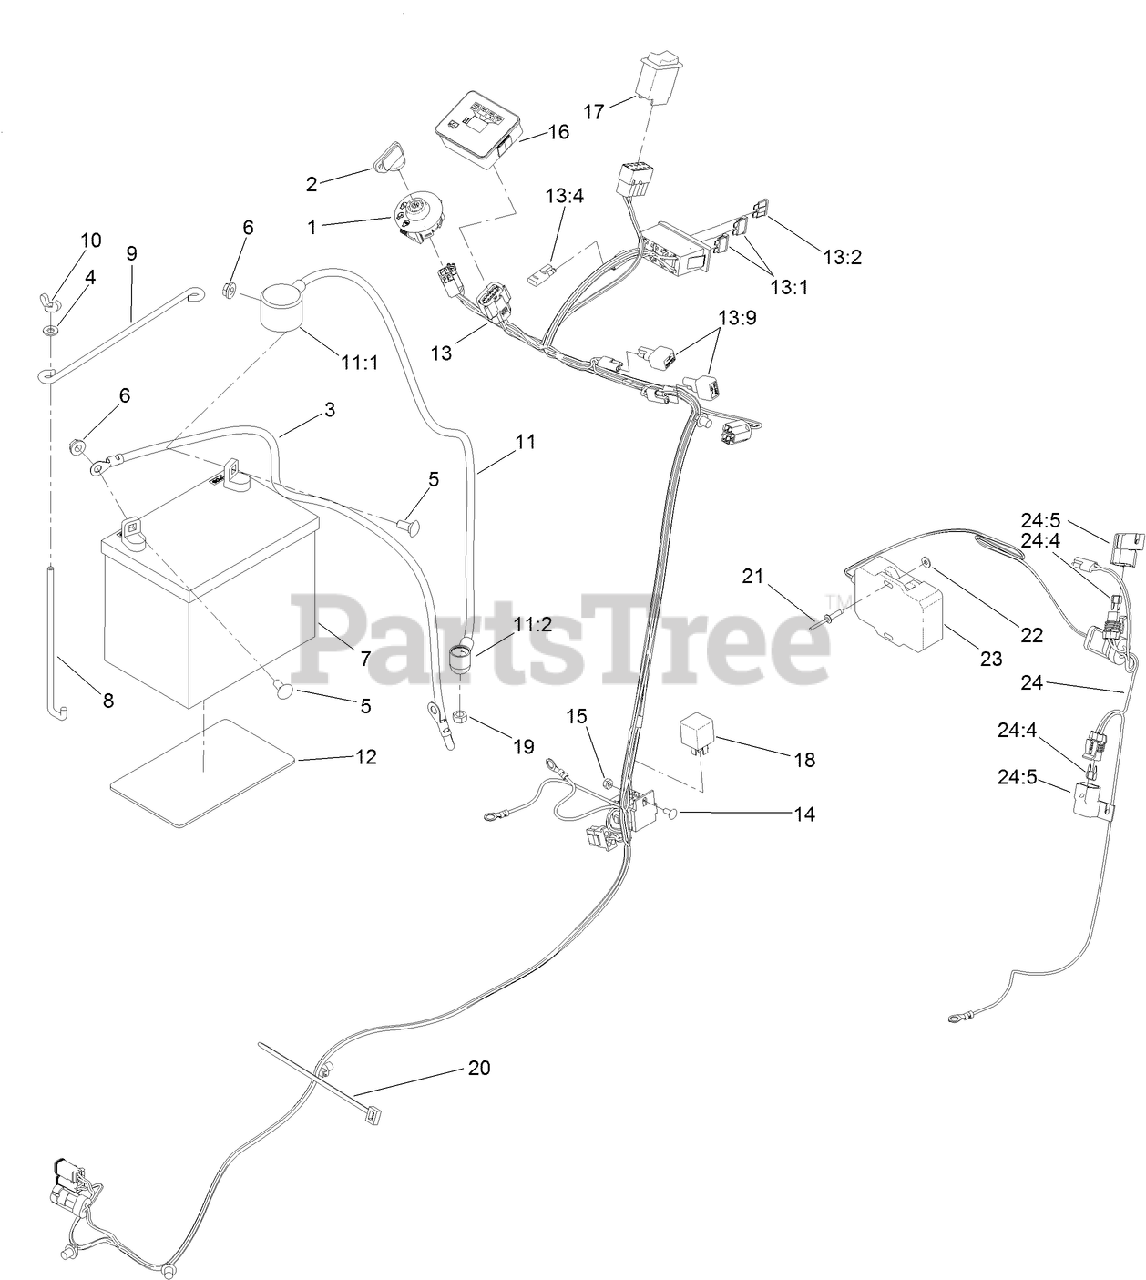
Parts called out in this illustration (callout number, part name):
1	SWITCH-IGNITION
2	KEY-IGNITION
3	CABLE-BATTERY, NEGATIVE
4	WASHER-FLAT
5	BOLT-CARR
6	NUT-HF
7	BATTERY (340 CCA, WET)
8	POST-BATTERY
9	ROD-HOLD DOWN, BATTERY
10	NUT-WING
11	POSITIVE BATTERY CABLE ASM
11:1	INSULATOR-BATTERY
11:2	INSULATOR-SOLENOID
12	PAD-SKID, ANTI
13	HARNESS-WIRE
13:1	FUSE-BLADE, 15 AMP
13:2	FUSE-BLADE, 7.5 AMP
13:4	CAP-PLUG
14	BOLT-CARR
15	NUT-LOCK, NI
16	MODULE, HOUR METER
17	SWITCH-ROCKER, 2 POLE
19	NUT-HEX
20	TIE-CABLE
21	RIVET-POP
22	WASHER-PLAIN
23	GPS ASM
24	HARNESS-WIRE, GPS
24:4	FUSE-MINI BLADE, 5 AMP
24:5	COVER-FUSE, SINGLE
